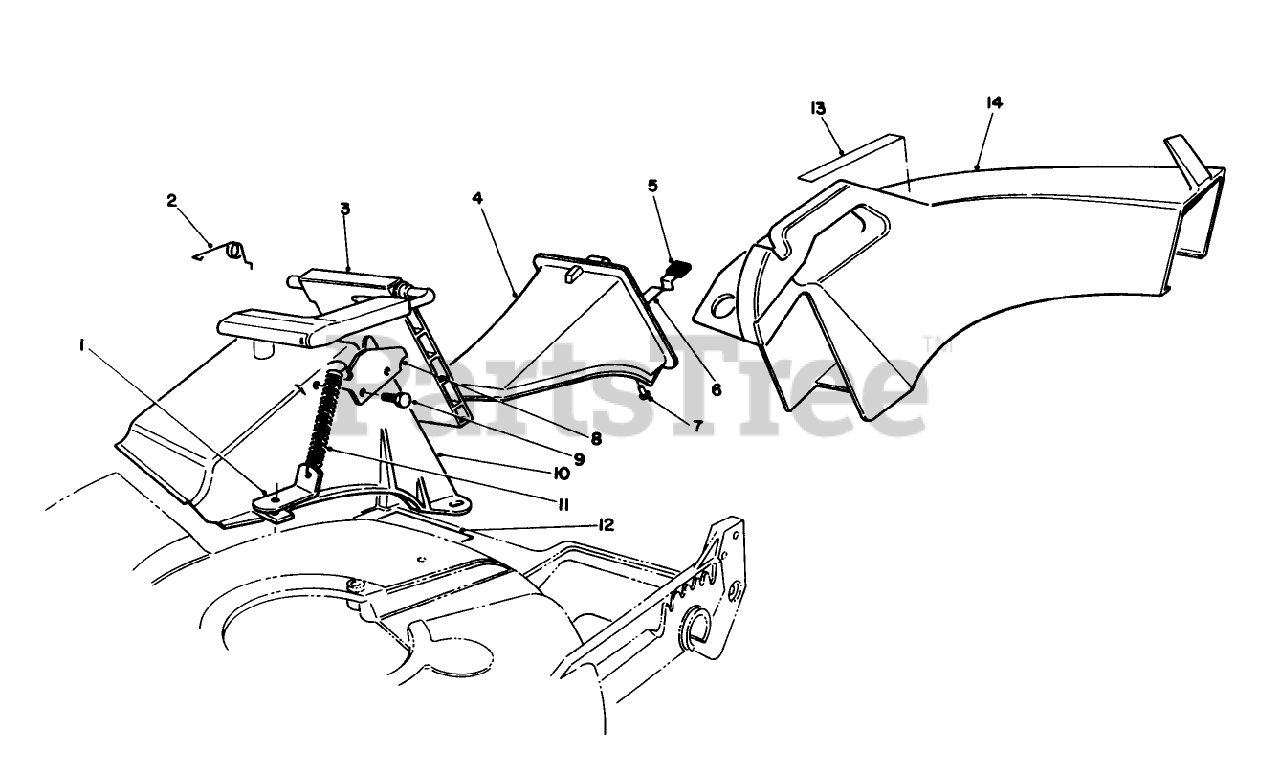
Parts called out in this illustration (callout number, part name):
2	RETAINER-DOOR
4	DISCHARGE PLUG ASM
5	GRIP-LATCH
6	LATCH-PLUG, DISCHARGE
7	RIVET-HEAD, FLAT
8	DOOR LATCH PLATE
9	SCREW-PLASTITE
10	DISCHARGE TUNNEL
11	BRIGGS-805197
